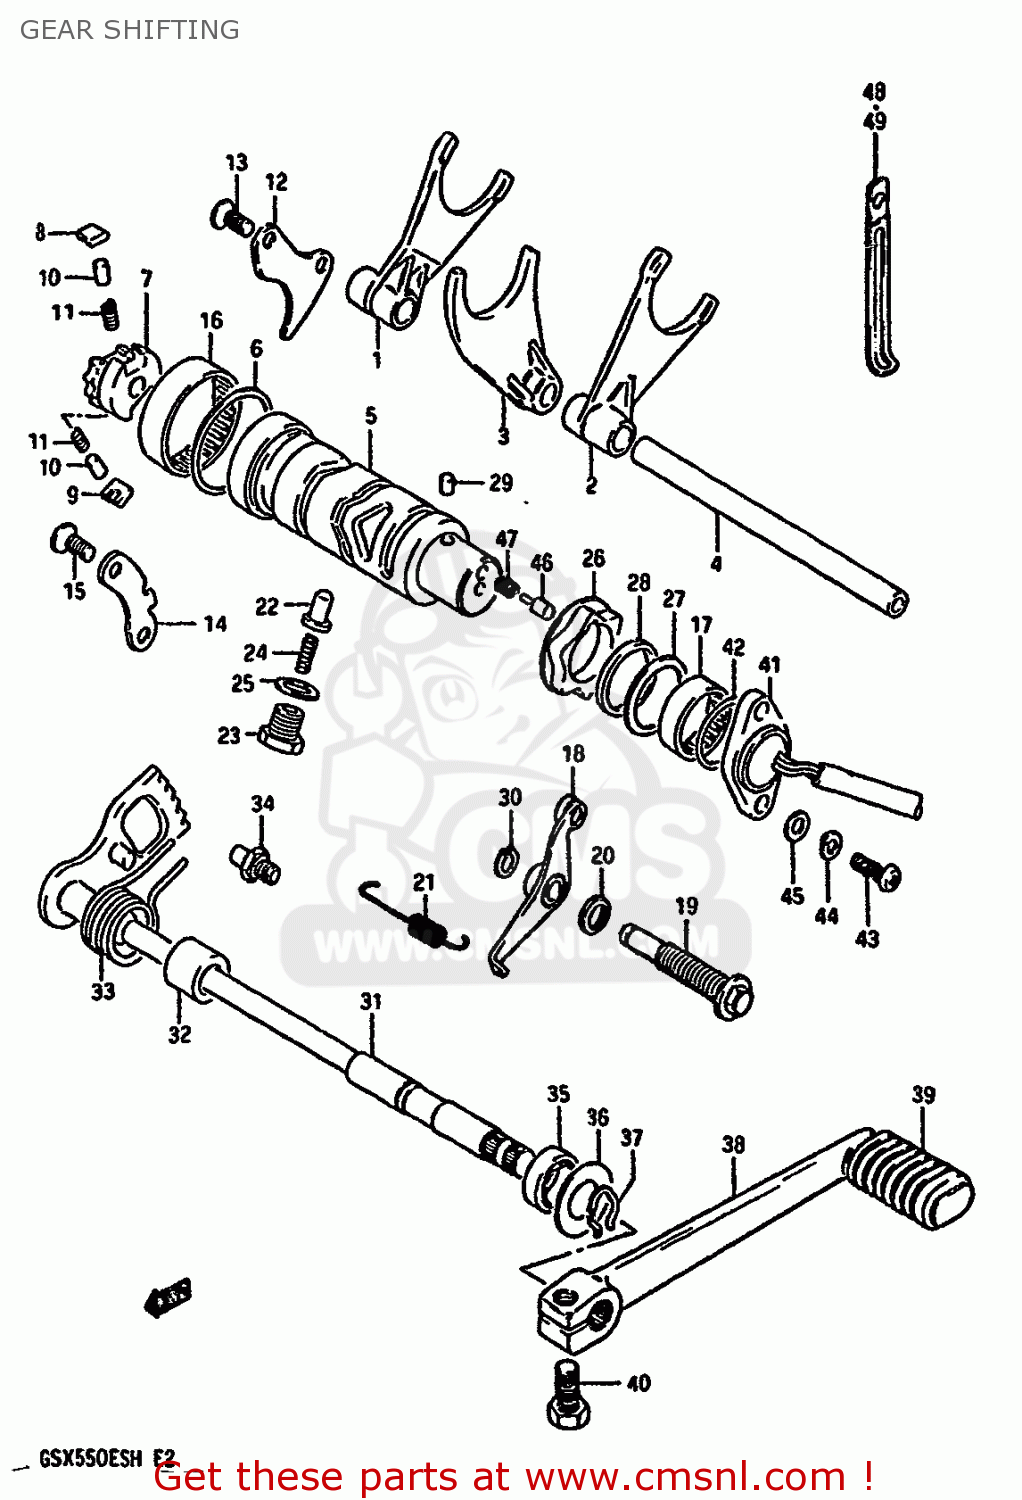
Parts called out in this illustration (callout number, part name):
1	FORK,GEAR SHIFT NO.1
2	FORK,GEAR SHIFT NO.2
3	FORK,GEAR SHIFT NO.3
4	SHAFT,GEAR SHIFT FORK
5	CAM,GEAR SHIFT
6	WASHER (40X49X1)
7	GEAR,GEARSHIFT CAM DRIVE
8	PAWL,GEAR SHIFT NO.1
9	PAWL,GEAR SHIFT NO.2
10	PIN(5X8)
11	SPRING
12	LIFTER,GEAR SHIFT PAWL
13	SCREW
14	GUIDE,GEAR SHIFT CAM
15	SCREW
16	BEARING(43X49X12)
17	BEARING(25X32X12)
18	STOPPER,GEAR SHIFTING
19	HOLDER,SHIFTING CAM STOPPER
20	GASKET(10X14X3.6) (NAS)
21	SPRING
22	STOPPER,GEAR SHIFTING
23	HOLDER,GEAR SHIFT CAM STOP SPR
24	SPRING
25	GASKET(14X19.2X2) (NAS)
26	PLATE,GEAR SHIFT CAM STOPPER
27	WASHER
28	WASHER
29	PIN 4X6
30	CIRCLIP
31	SHAFT,GEAR SHIFT
32	SPACER(12X20X15.3)
33	SPRING
34	STOPPER,GEAR SHIFT CAM
35	OIL SEAL
36	WASHER (12.5X27X1.6)
37	SPRING,RETAINER
38	LEVER ASSEMBLY,GEAR SHIFTING
39	RUBBER,PEDAL
40	BOLT
41	TERMINAL BASE ASSY,GEAR SHIFT
42	O-RING (D:2.4 ID:26.2)
43	SCREW(5X14)
44	LOCK WASHER
45	WASHER
46	PIN(5X15.5)
47	SPRING
48	CLAMP L:35
49	CLAMP
